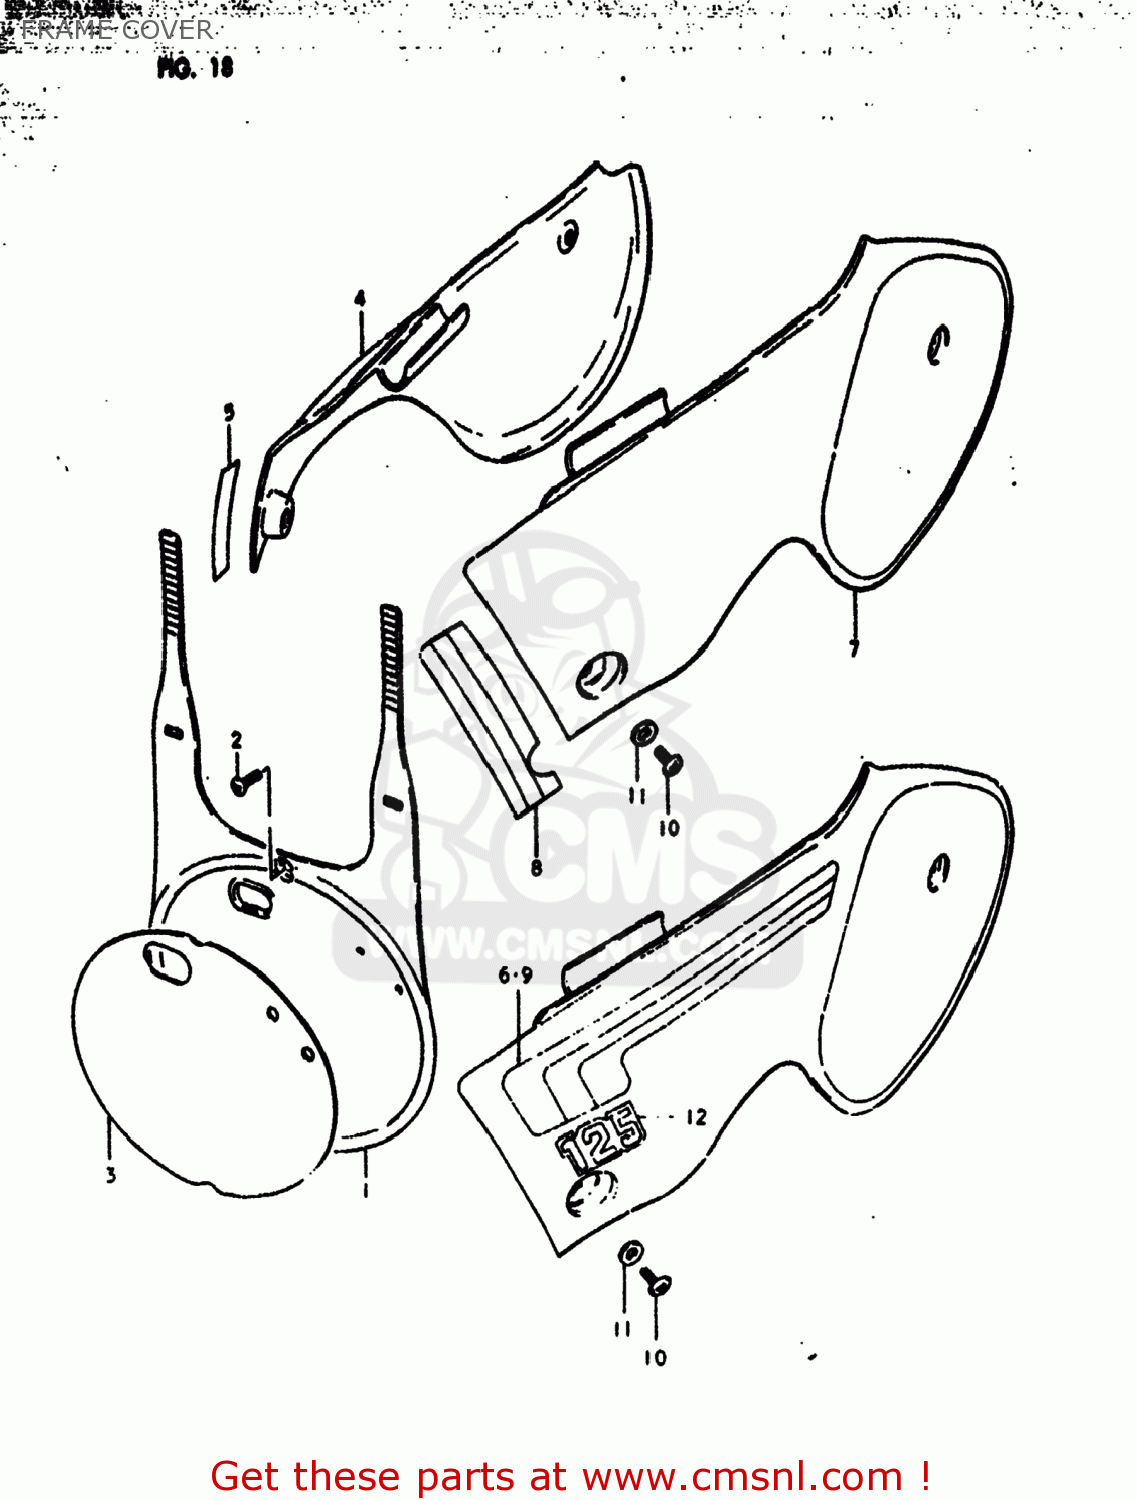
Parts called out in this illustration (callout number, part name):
1	PLATE,FR NUMBER
2	(5X20) CROSS SCREW
3	EMBLEM,FRONT NUMBER PLATE
4	COVER,FRAME,RIGHT
5	TAPE, RH
6	TAPE,FRAME COVER
7	COVER,FRAME,L(YELLOW)
8	TAPE,FRAME COVER,LEFT STRIPE
9	TAPE,FRAME COVER
10	SCREW 6X12
11	WASHER
12	EMBLEM
